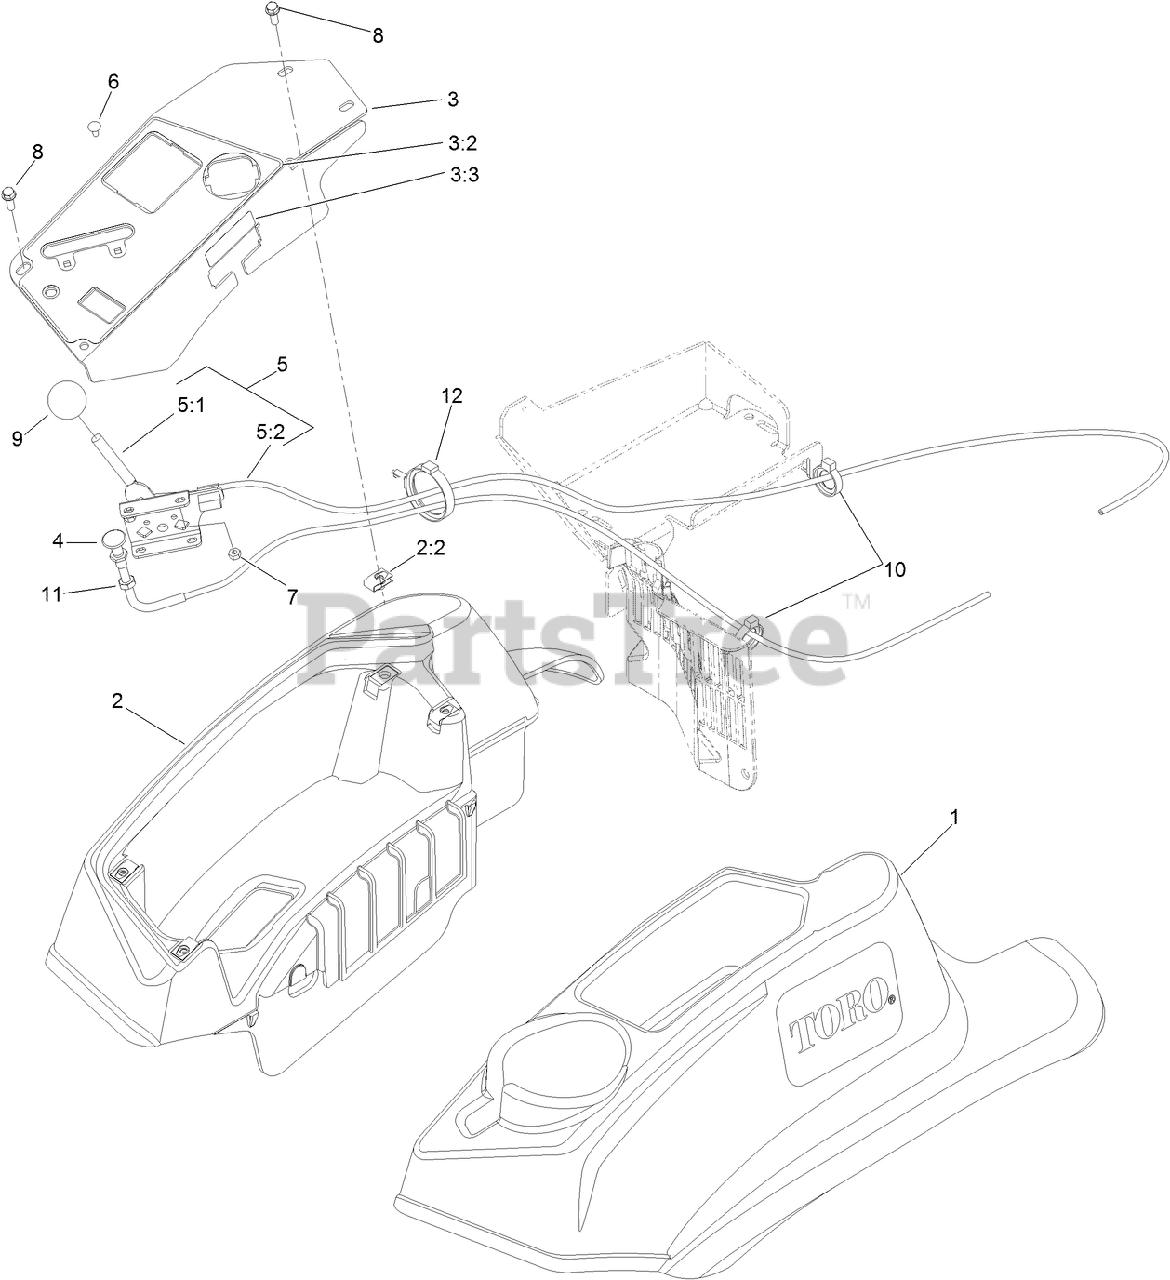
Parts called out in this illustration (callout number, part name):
1	CONSOLE-LH
2	RH CONSOLE ASM
3	CONTROL PANEL ASM
3:2	DECAL-CONTROL PANEL
3:3	DECAL-FUSES
4	CHOKE CONTROL ASM
5	THROTTLE CONTROL ASM
5:1	LEVER-THROTTLE
5:2	CABLE-THROTTLE
6	BOLT-CARR
7	NUT-LOCK, NI
8	SCREW-HWH
9	KNOB-BALL
10	CLAMP-HOSE
11	NUT-HJ
12	CLAMP-HARNESS
